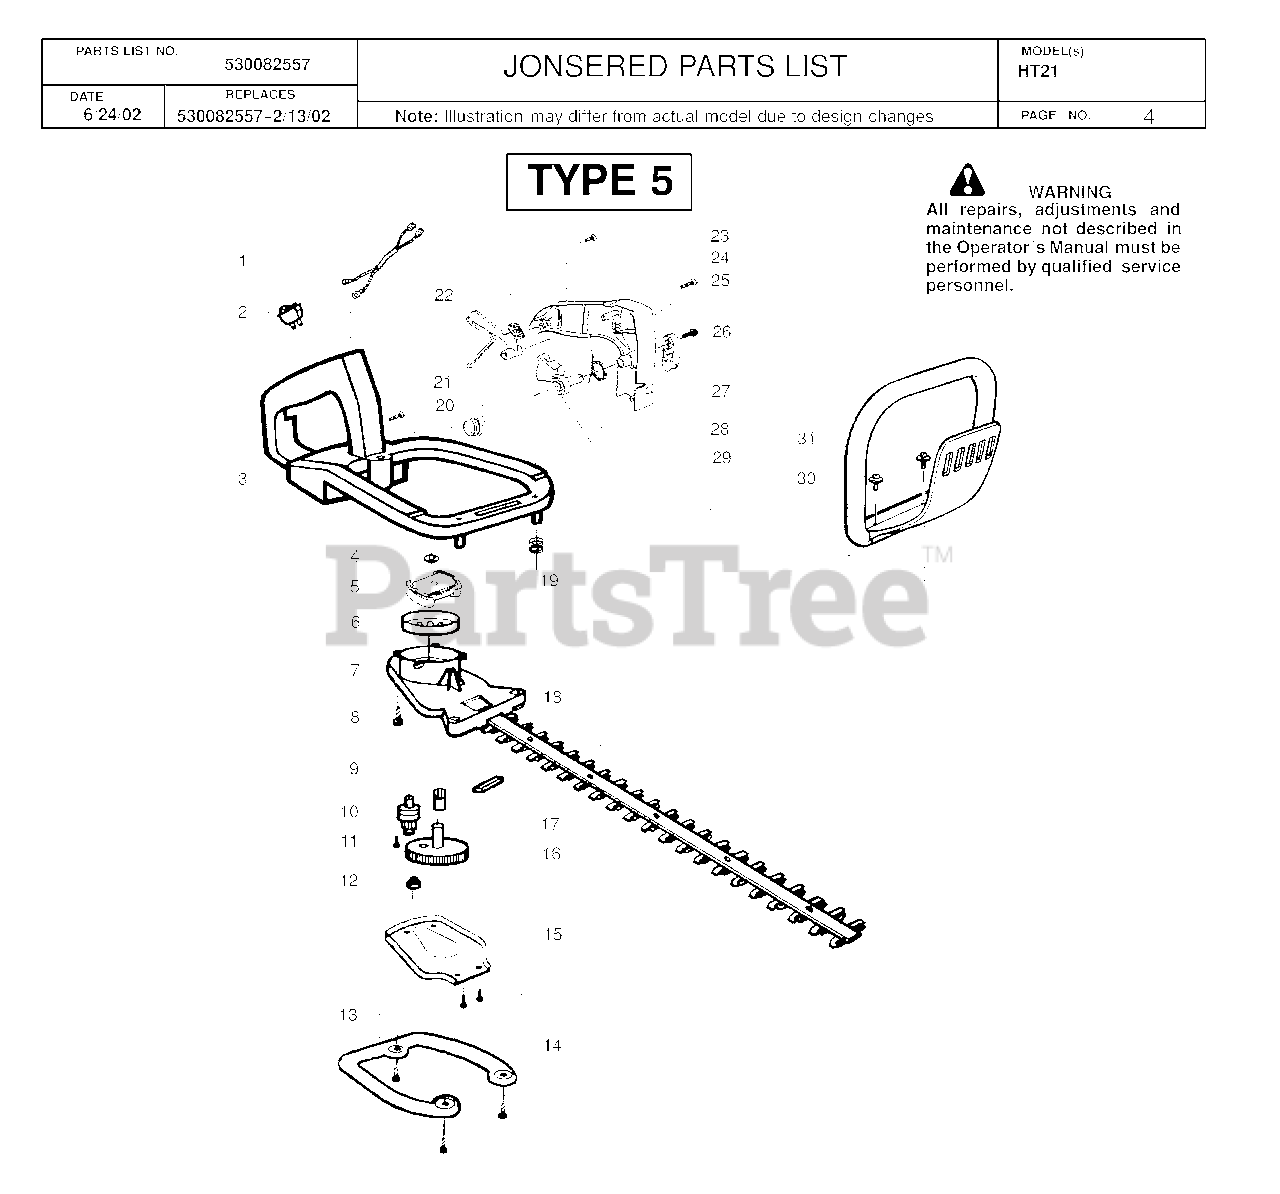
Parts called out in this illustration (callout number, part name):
3	ASSY-REAR HANDLE & TANK
4	WASHER FLAT
6	CLUTCH DRUM
7	GEARBOX ASSY
8	SCREW-10-14 X 13/16 (PL
11	SCREW-10-16 X 1/2, TYPE 2
12	BLADE BUSHING
13	ISOLATOR PLATE
15	PLATE-GEARBOX COVER
18	BLADE ASSEMBLY
19	ANTIVIBE MOUNT
20	COVER
21	SCREW-10-16 X 1-3/8 PLA
22	LOCKOUT-THROTTLE
26	SCREW 8-16 X 9/16 (PLAS
